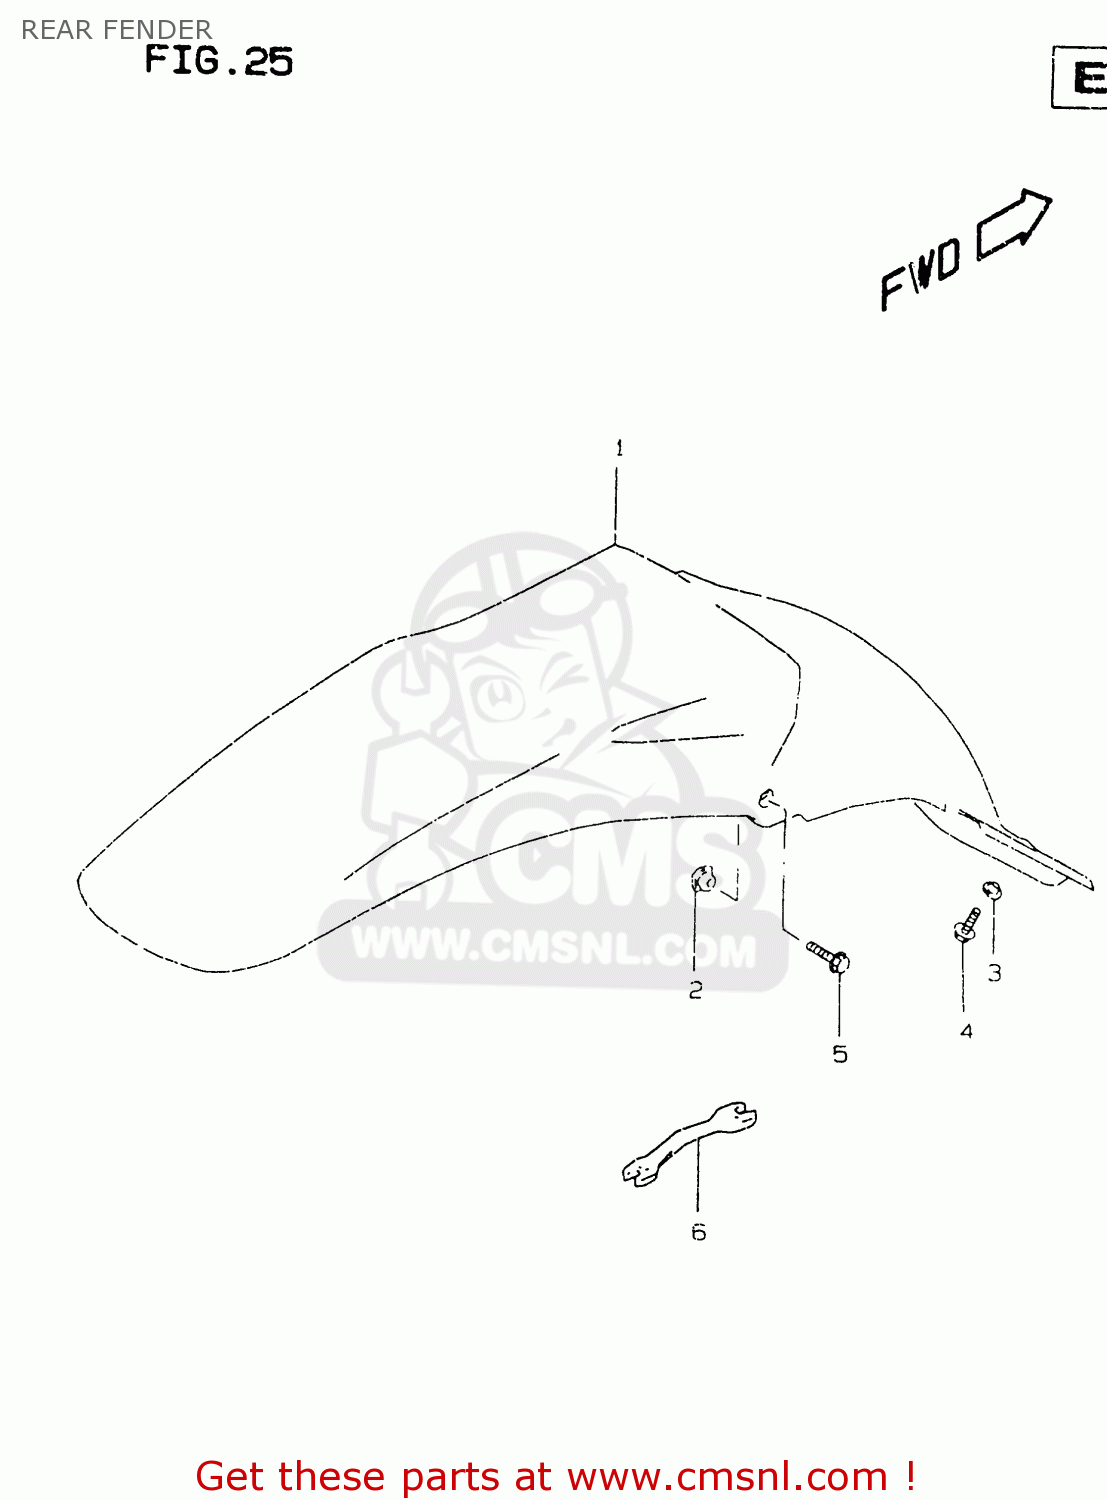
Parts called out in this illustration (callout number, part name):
1	FENDER,RR
2	NUT
3	WASHER
4	BOLT
5	SCREW
6	SPANNER,OPEN
